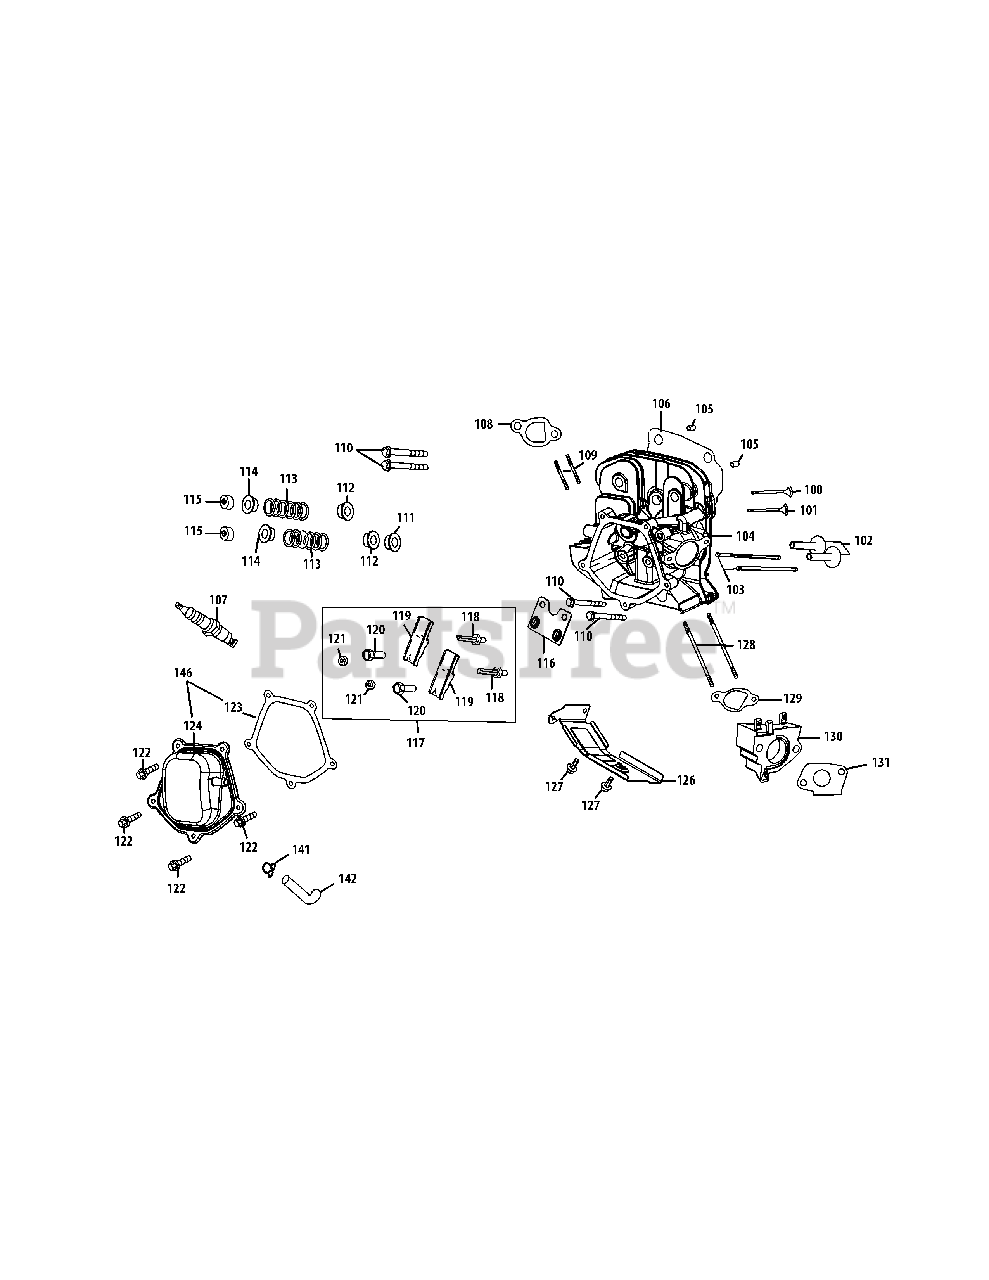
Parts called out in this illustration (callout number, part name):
100	Exhaust Valve
102	Tappet
104	Cylinder Head Assembly
105	Dowel Pin 12×20
106	Gasket,Cylinder Head
107	Spark Plug
108	Exhaust Pipe Gasket
109	Muffler Stud M8×48.5
109	Muffler Stud Assembly
110	Bolt M10×1.25×80
111	Intake Valve Seal
112	Valve Spring Retainer
113	Valve Spring
114	Retainer,Ex.Valve Spring
115	Adjuster,Exh Valve
116	Push Rod Guide
117	Rocker Arm Assembly
120	Adjusting Nut ,Valve
121	Nut,Pivot Locking
122	Valve Cover Bolt
123	Valve Cover Gasket
128	Carburetor Stud M6-8×106
129	Intake Gasket
130	Carburetor Insulator
131	Carburetor Gasket
142	Breather Hose
146	Valve Cover Kit
